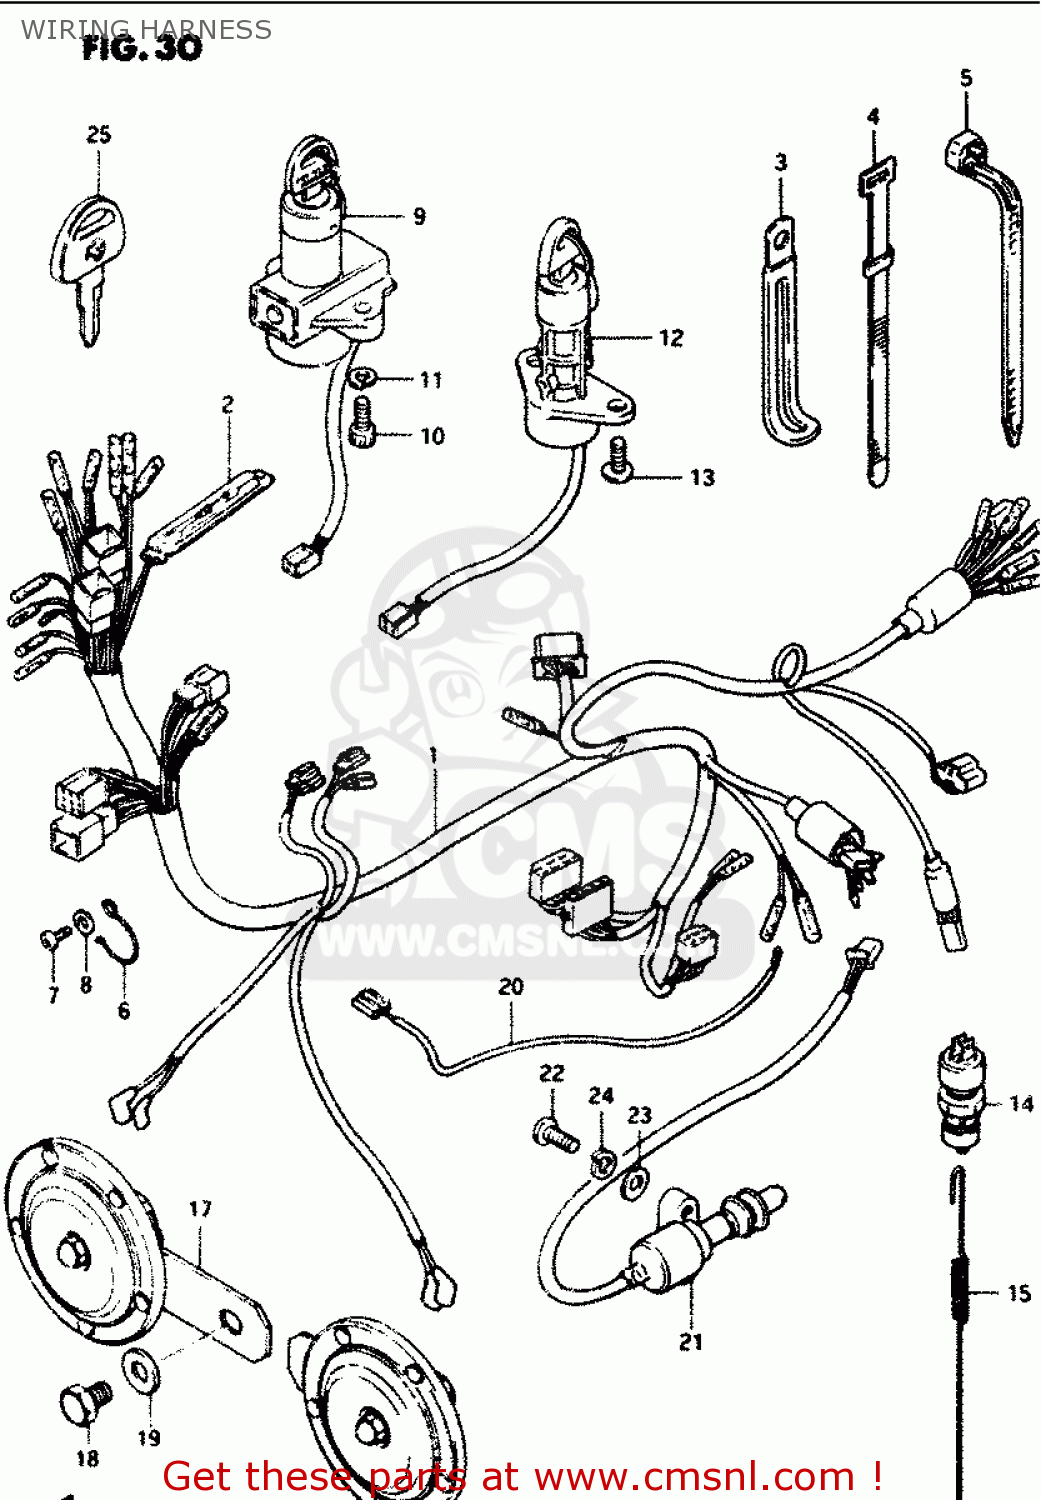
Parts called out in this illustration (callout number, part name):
1	WIRING HARNESS
2	DIODE
3	CLAMP
4	CLAMP(L:120)
5	CLAMP(L:165)
6	CLIP,WIRING HARNESS
7	SCREW
8	WASHER
9	SWITCH ASSY,IGNITION
10	BOLT
11	WASHER,LOCK
12	SWITCH ASSY,IGNITION
13	SCREW 6X12
14	SWITCH ASSEMBLY,STOP LAMP
15	SPRING
16	HORN ASSEMBLY,LOW PITCH
17	HORN ASSEMBLY,HIGH PITCH
18	BOLT
19	WASHER
20	WIRE,OIL PRESSURE SWITCH LEAD
21	SWITCH ASSEMBLY,SIDE STAND
22	BOLT
23	WASHER
24	LOCK WASHER
25	KEY,BLANK
